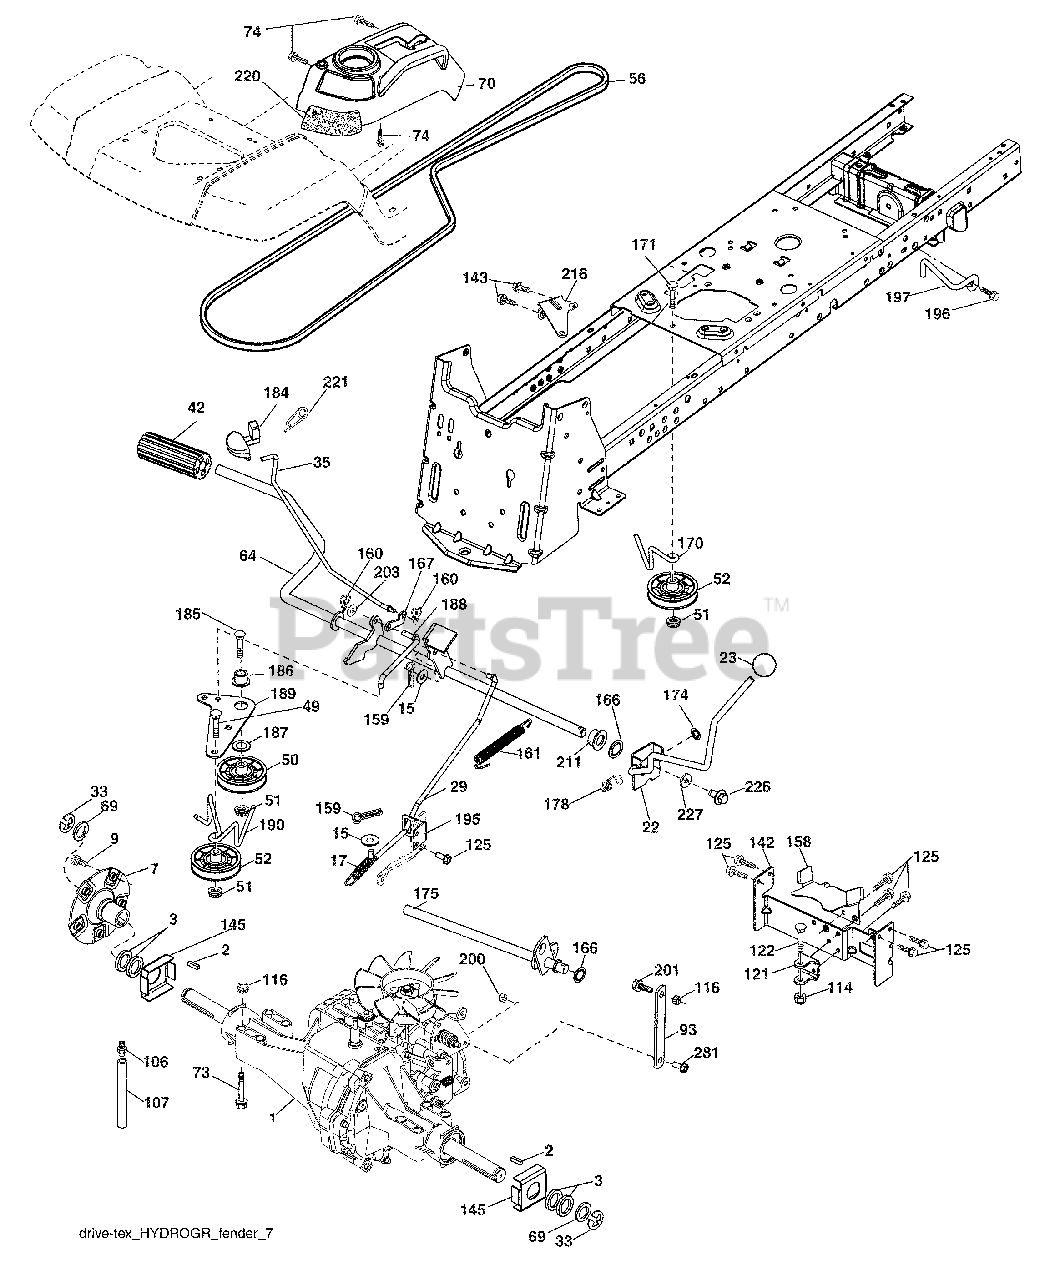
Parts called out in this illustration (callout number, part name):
2	Key 1/4 x 2.5
7	Hub Asm. Wheel
9	Bolt Hub Wheel
15	Washer 13/32 x 13/16 x 16 Ga.
17	Spring, Brake
22	Shifter Rod
29	Rod, Brake
35	Rod, Brake, Park
42	Cover, Foot Pedal
50	Pulley Idler Flat
51	Lock Nut 3/8-16
52	Idler V-Groove 910" Offset
56	V-Belt, Drive
64	Shaft Asm. Pedal Brake Control
69	Washer 11/32 x 1-5/8 x 16 Ga.
70	Control Asm.
73	Bolt Hex Flghd 5/16-18 x 3.00
74	Screw 1/4 x 1/2
93	Link Shift
106	Cap Asm. Vent
114	Nut Lock Hex w/Insert 5/16-18 unc
116	Nut Lock Hex Flange 5/16-18
121	Bracket Strap Torque
122	Bolt 5/16 - 18 x 2.50
125	Screw 5/16-18 x 3/4
142	Strap Torque
143	Screw Thdrol 5/16-18 x 1/2
145	Washer Axle flange
158	Keeper Belt
159	Pin Cotter 1/8 x 3/4
160	Retainer Clip
161	Spring, Return, Clutch
166	Nut Push .625
167	Latch Brake Parking
170	Keeper Belt Centerspan
175	Shaft Asm Shift
178	Spring Shift
184	Handle Parking Brake
185	Bolt Rdhd Sqnk 3/8-16 x 2-1/2
186	Spacer Retainer
187	Washer
188	Link Clutch Ground Drive
189	Bellcrank Ground Drive
190	Keeper Bellcrank Ground Dr.
195	Bracket Rod Brake
196	Screw 3/8-16 x 1
197	Bracket Clutch Anti-Rotation
200	Nut Centerlock 5/16-18
201	Bolt Shoulder 5/16-18 unc
203	Washer 11/32 x 11/16 x 16 Ga.
216	Bracket Pulley Idler
220	Reflector RH
221	Retainer Spring Clip Handle
226	Bolt Fin Hex 7/16 - 14 x 1 Gr. 5
227	Washer Serrated
281	Shoulder Bolt
